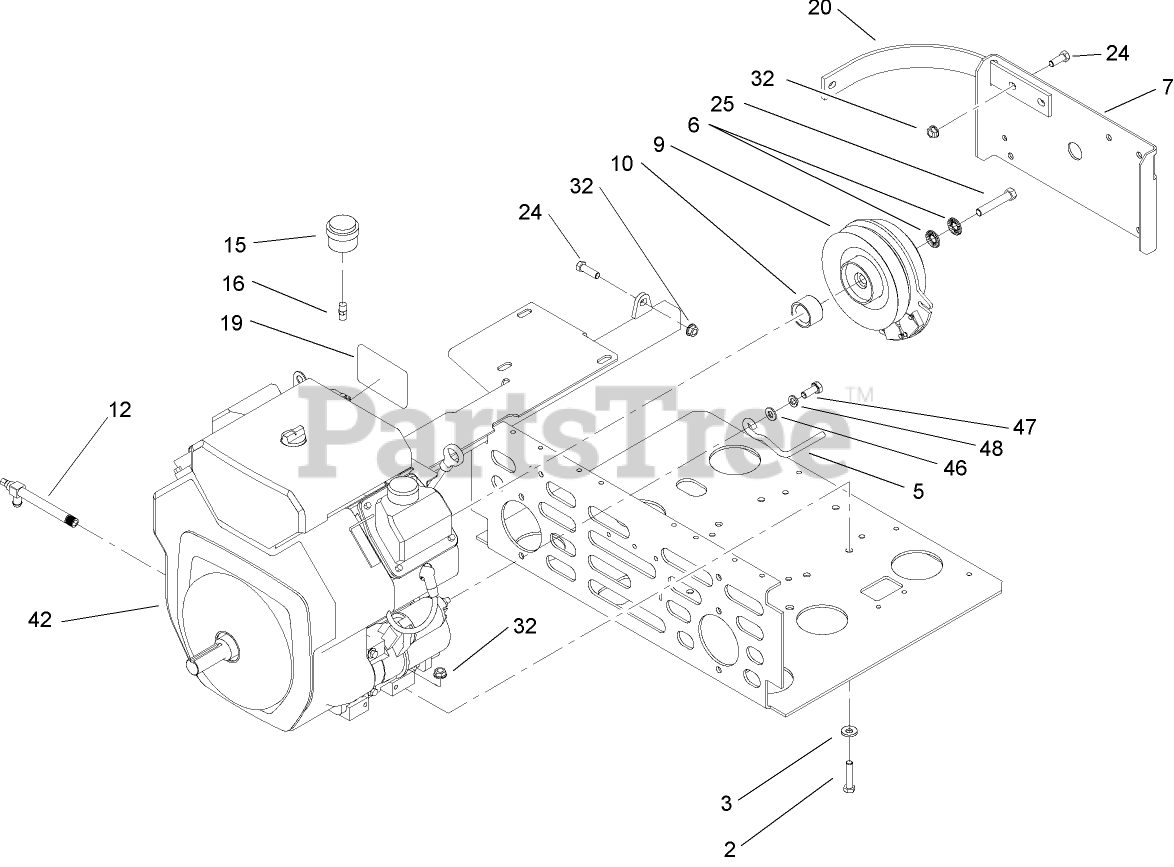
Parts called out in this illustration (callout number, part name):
2	SCREW-HH
3	WASHER-BELLEVILLE
5	ROD-BELT
6	WASHER-SPRING
7	GUARD-CLUTCH
9	CLUTCH
10	SPACER-CLUTCH
12	VALVE-OIL DRAIN, LONG
15	INDICATOR-FILTER, AIR
16	ADAPTER-INDICATOR
20	STRAP-GUARD
24	SCREW-HH
25	SCREW-HH
32	NUT-HHF, WHIZ
46	WASHER-FLAT
47	SCREW-HH
48	WASHER-BELLEVILLE
